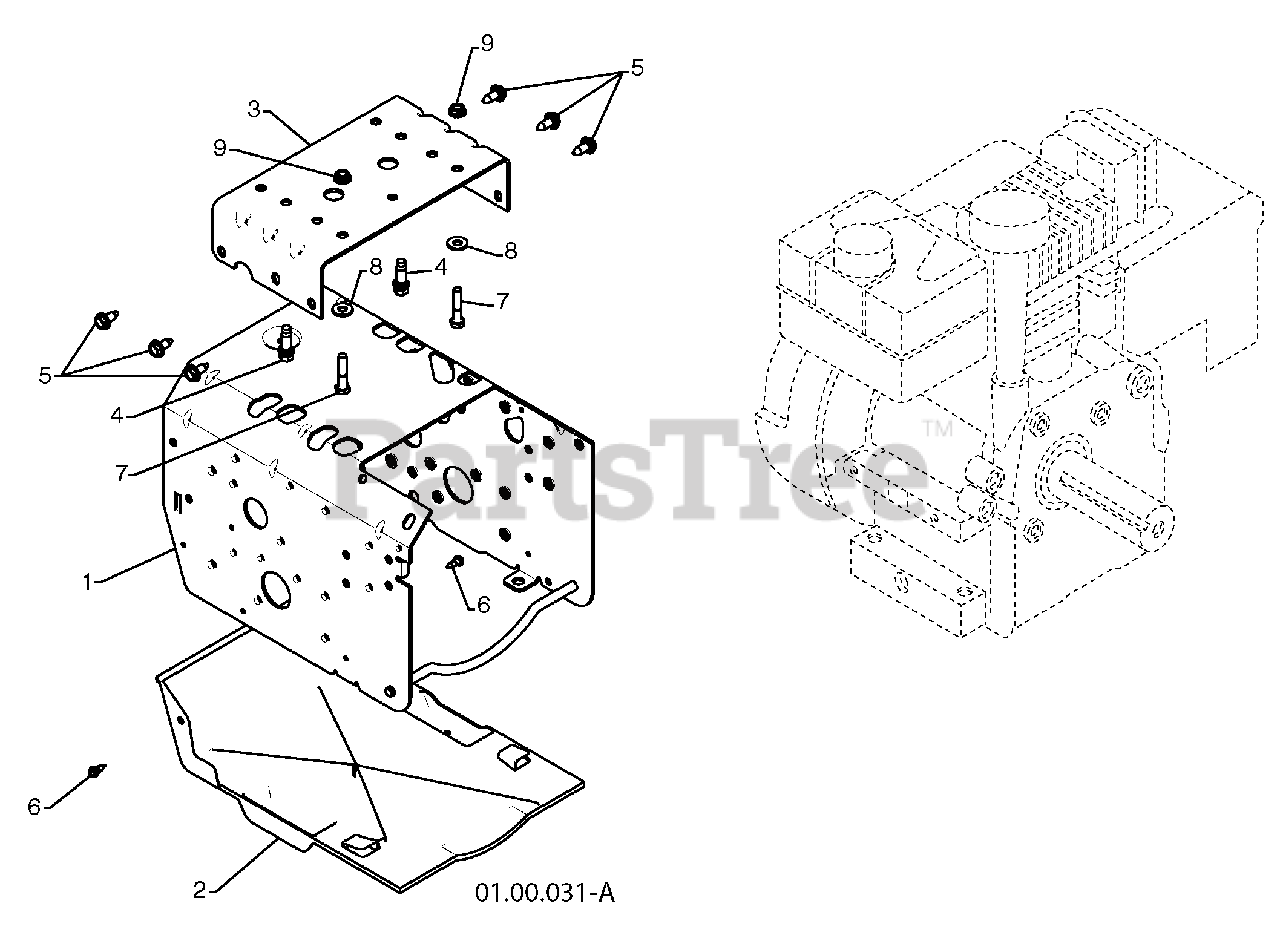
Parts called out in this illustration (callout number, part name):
1	WELDMENT FRAME
2	BOTTOM PAN
3	ENGINE MOUNT PLATE
4	BOLT 3/8-16
5	SCREW 5/16-18 X .750
6	SCREW 10-24 X .625
7	SCREW 5/16-18 X 1.50
